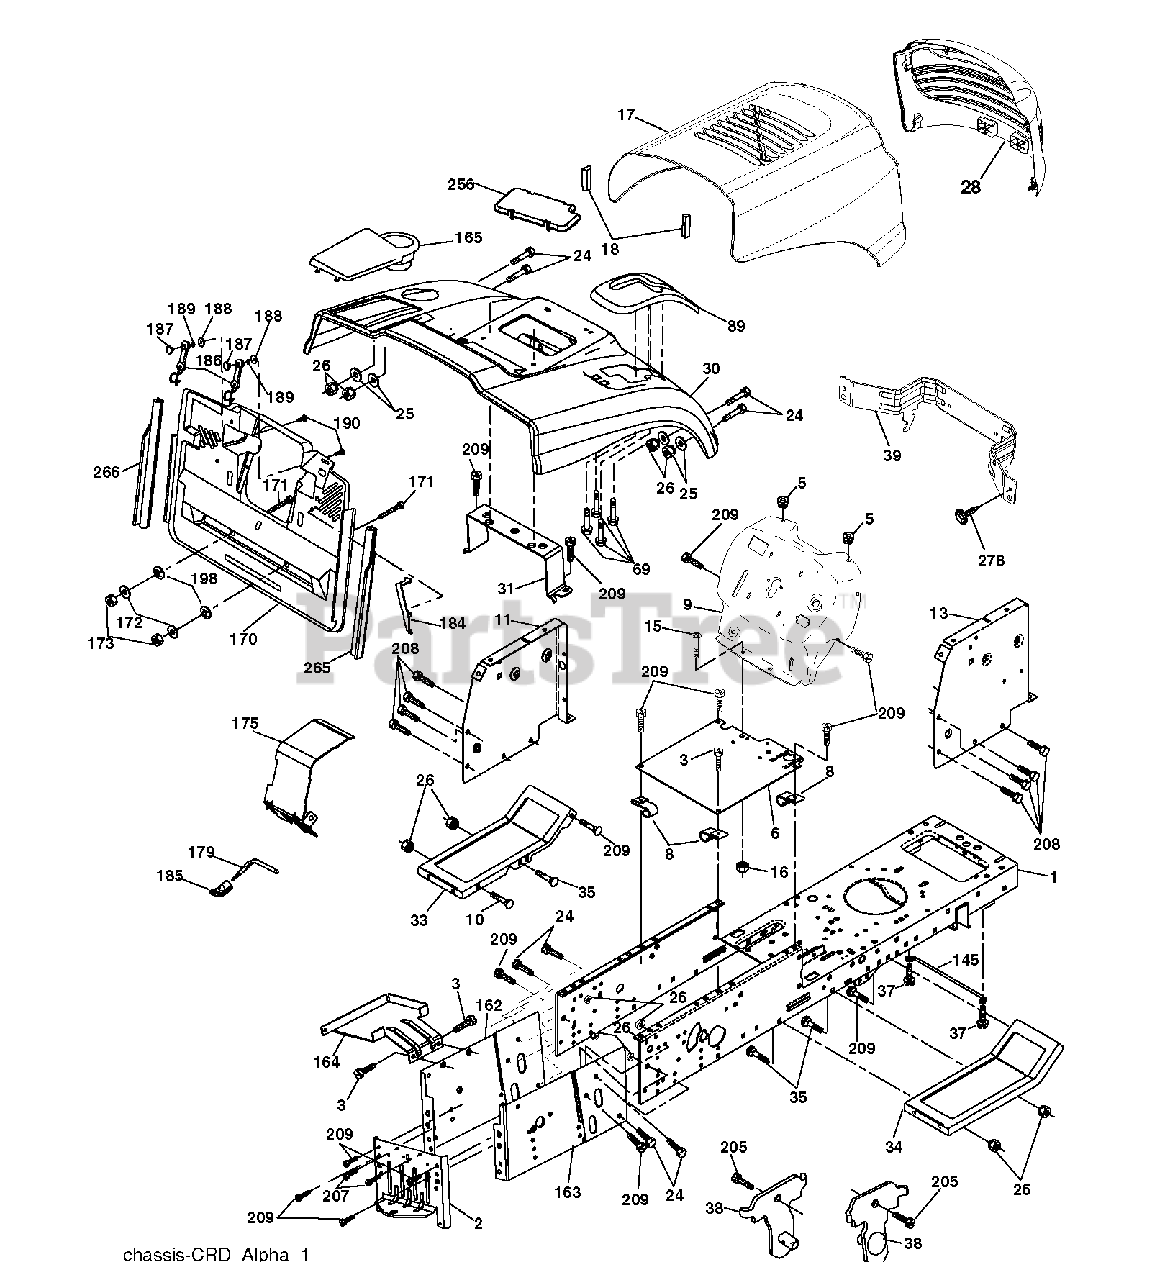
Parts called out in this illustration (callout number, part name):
1	CHASSIS
3	SCREW 3/8-16X3/4
5	BUMPER.RUBBER.HOOD
8	CLIP,INSULATOR
9	FENDER LT SH
10	BOLT D
11	PANEL.DASH.LH.LTX
13	PANEL DASH RH
16	NUT
17	GRILLE.ALPHA.LT.NO LIGHTS
18	BUMPER.HOOD.LARGE.1.75"
25	WASHER
26	NUT
28	GRILLE.ALPHA.LT.NO LI
30	FENDER.PNT.CRD.MS-417.2005
31	BRACKET SUPPORT FENDER
33	FOOTREST.PNT.RH
39	BRACKET.PIVOT.ALPHA.LT
69	SCREW.HI-LO.CONSOLE
89	CONSOLE.CRD.AUTO.BLACK
145	ROD.PIVOT.HOOD
164	SUPPORT
165	FENDER.PNT.CRD.
171	BOLT
172	WASHER
184	BRACKET.ACTUATOR.BAGGER.SRD
187	WELDNUT
207	SCREW, 5/16-18 X 1/2
208	SCREW 3/8-16X1/2
209	SCREW, 3/8-16X3/4
256	FENDER.PNT.CRD
278	SCREW.#10 X 0.750.BOS THREAD
